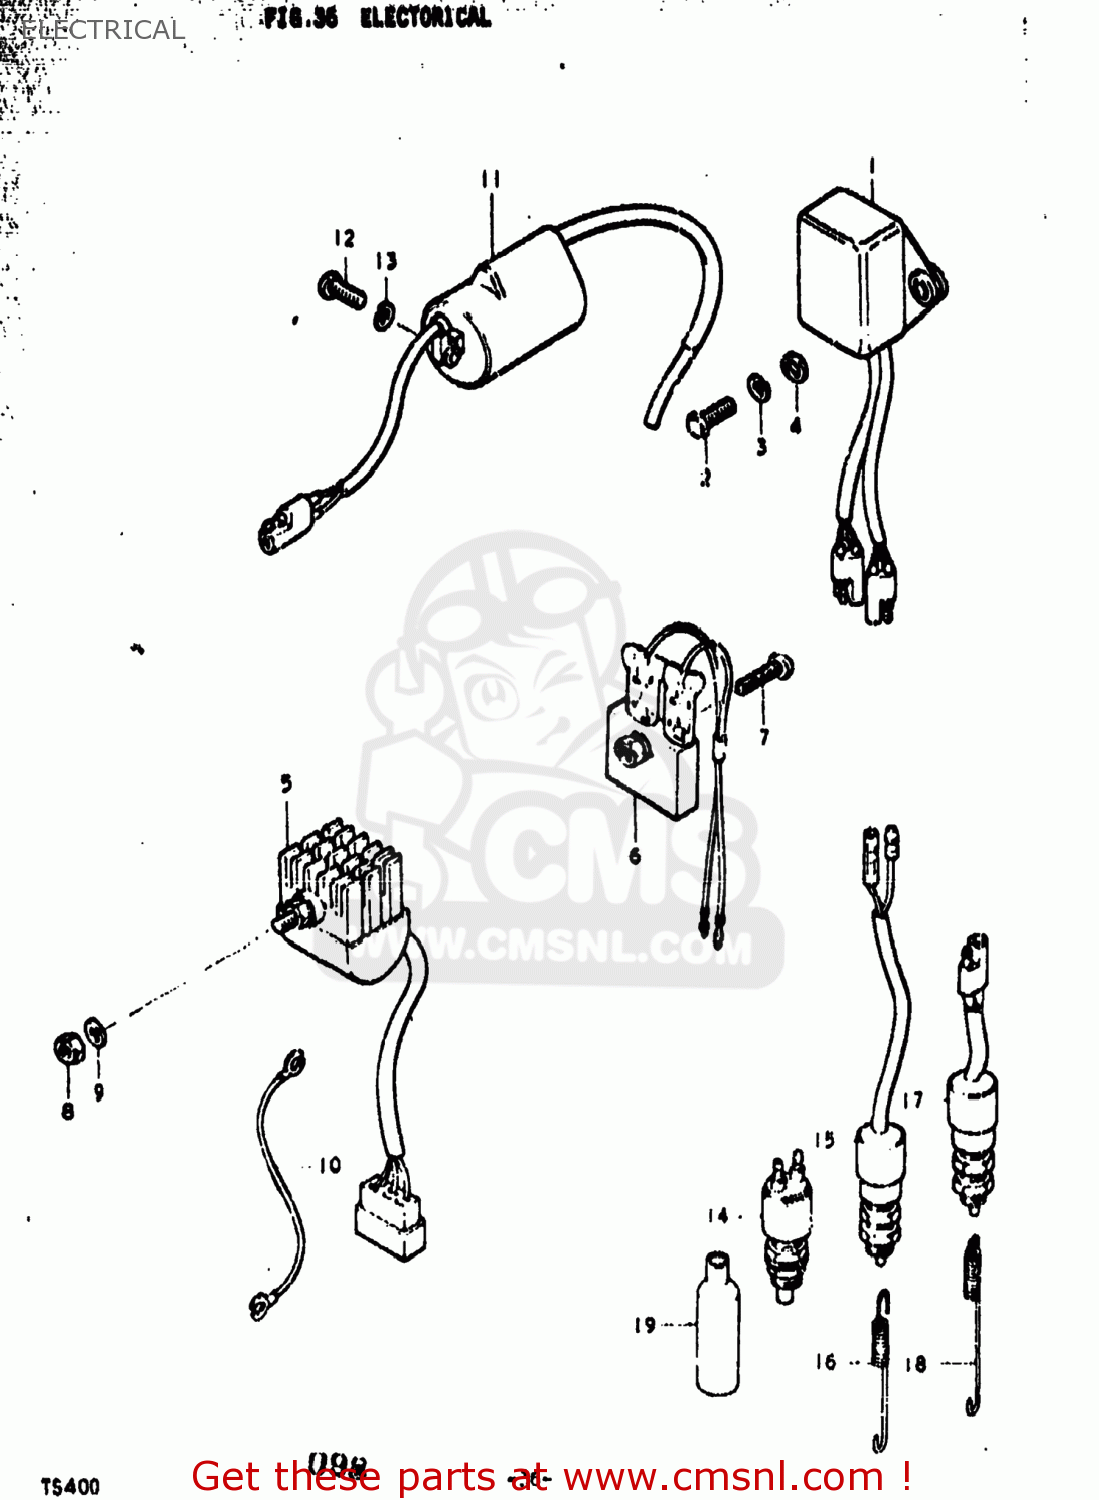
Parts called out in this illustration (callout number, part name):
2	BOLT(6X20)
3	LOCK WASHER
4	WASHER
5	RECTIFIER ASSY
6	RECTIFIER ASSEMBLY
7	SCREW
8	NUT
9	LOCK WASHER
10	WIRE
11	COIL ASSEMBLY,IGNITION
12	SCREW
13	LOCK WASHER
14	SWITCH ASSY,BRAKE LAMP
15	SWITCH ASSEMBLY,STOP LAMP
16	SPRING
17	SWITCH ASSY, STOP LAMP
18	SPRING
19	BOOT,WIRING HARNESS
